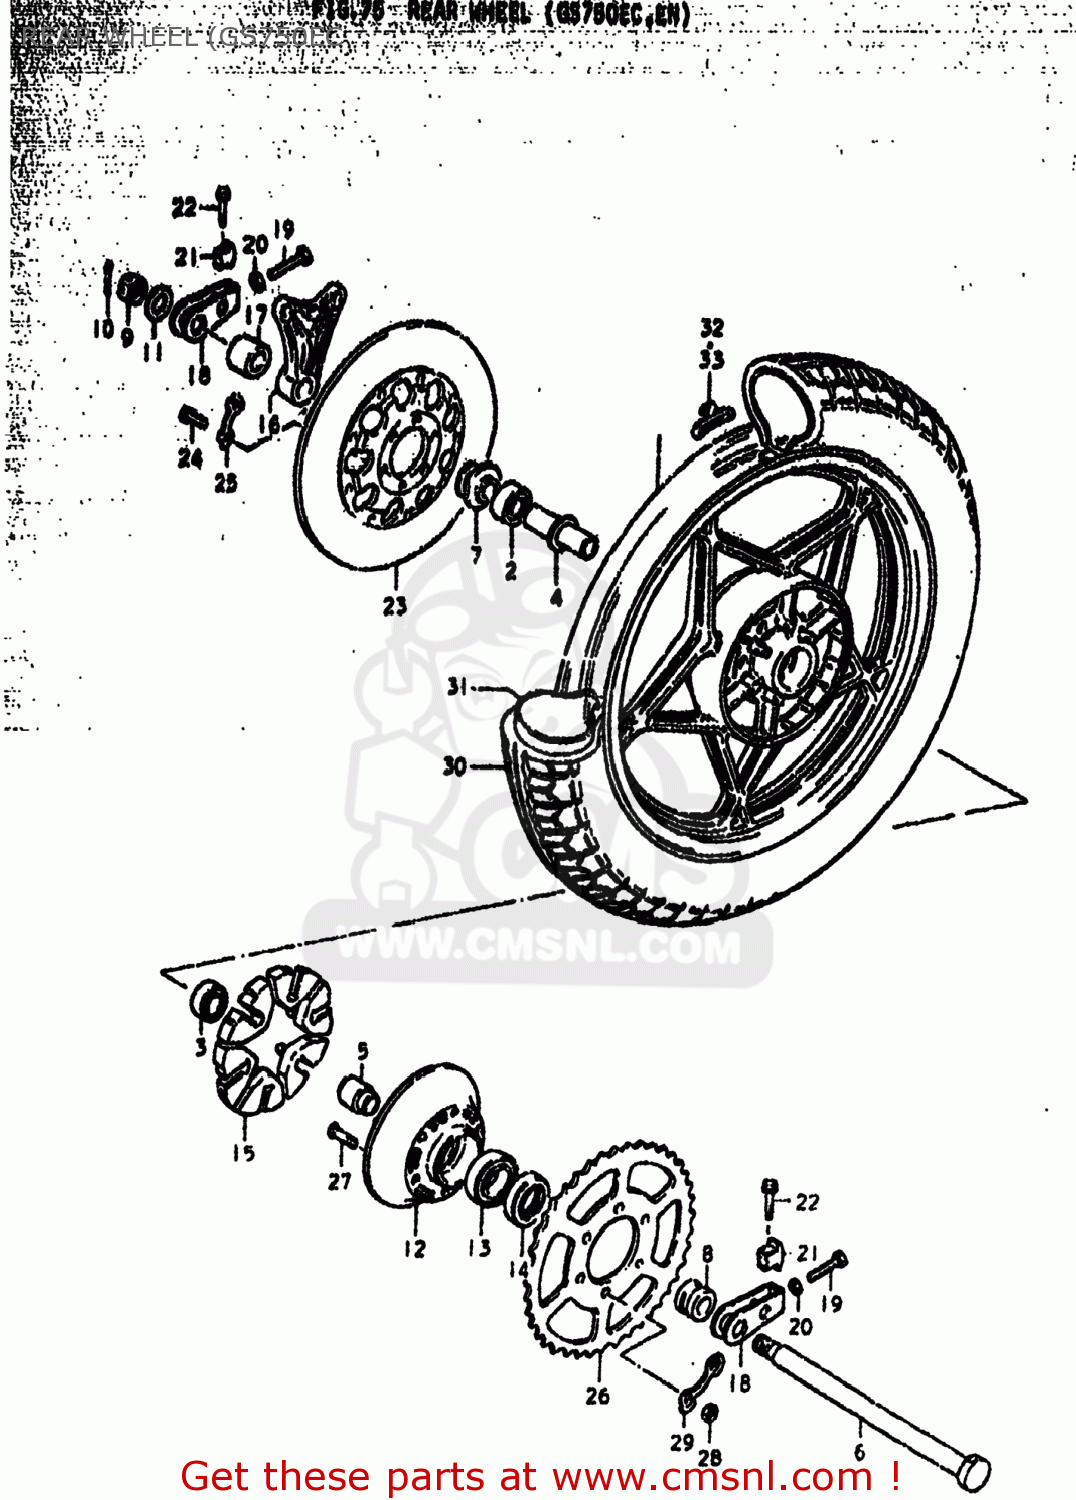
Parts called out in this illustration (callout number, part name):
1	WHEEL, REAR
2	BEARING, RH
3	BEARING, LH
4	SPACER,REAR HUB BEARING
5	SPACER,REAR HUB BEARING
6	AXLE,REAR
7	SPACER,REAR AXLE
8	SPACER(20X33X28.3)
9	NUT 18MM
10	PIN,COTTER
11	WASHER(19X34X4)
12	DRUM,REAR SPROCKET MOUNT
13	BEARING
14	SEAL,OIL(33X62X7)
15	ABSORBER,REAR HUB SHOCK
16	BRACKET,RR,CALIPER
17	SPACER(20X38X12)
18	ADJUSTER,CHAIN
19	BOLT
20	NUT
21	SUPPORTER,CHAIN ADJUST
22	BOLT (8X40)
23	DISC,BRAKE
24	BOLT(8X30)
25	WASHER
26	SPROCKET,REAR
27	BOLT
28	NUT
29	WASHER
30	TIRE
31	TUBE ASSEMBLY,WHEEL,INNER
32	BALANCER,WHEEL
33	BALANCER,WHEEL
